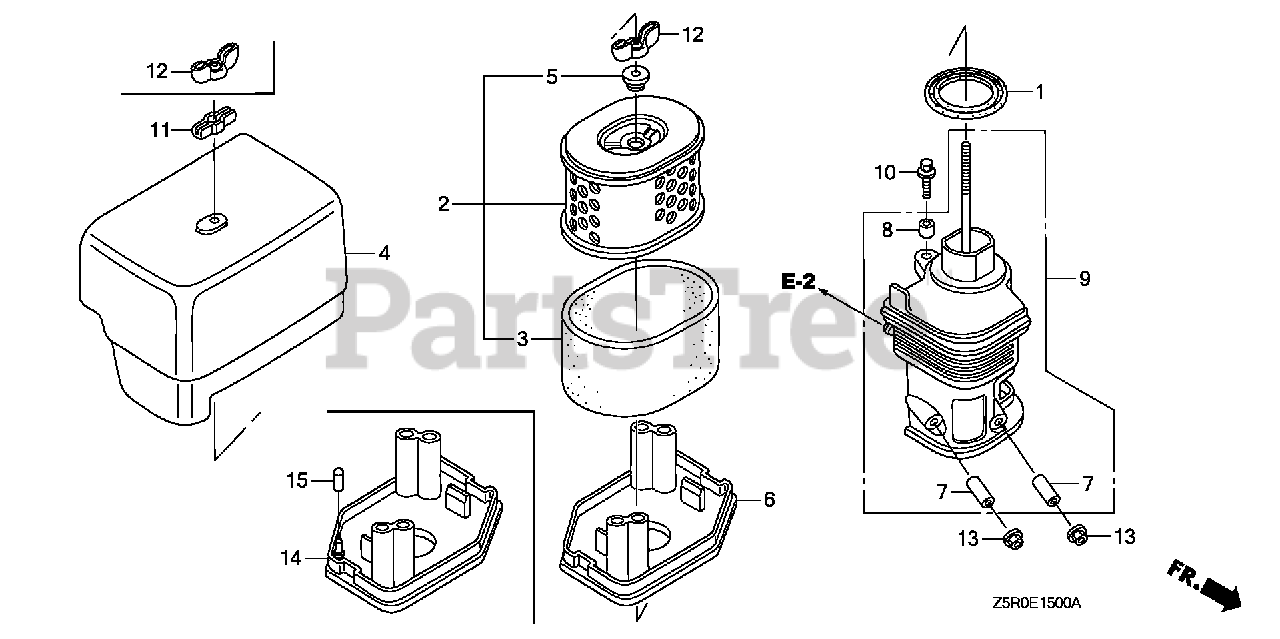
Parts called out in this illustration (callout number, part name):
1	GASKET, ELBOW
2	ELEMENT, AIR CLEANER
3	FILTER (OUTER)
4	COVER, AIR CLEANER
5	GROMMET, AIR CLEANER
7	COLLAR, AIR CLEANER
8	COLLAR B, AIR CLEANER
9	ELBOW, AIR CLEANER
10	BOLT-WASHER (6X22)
12	WINGNUT, TOOL BOX SETTING
13	NUT, FLANGE (6MM)
14	NOSE, MUFFLER
15	CAP, SEALING
